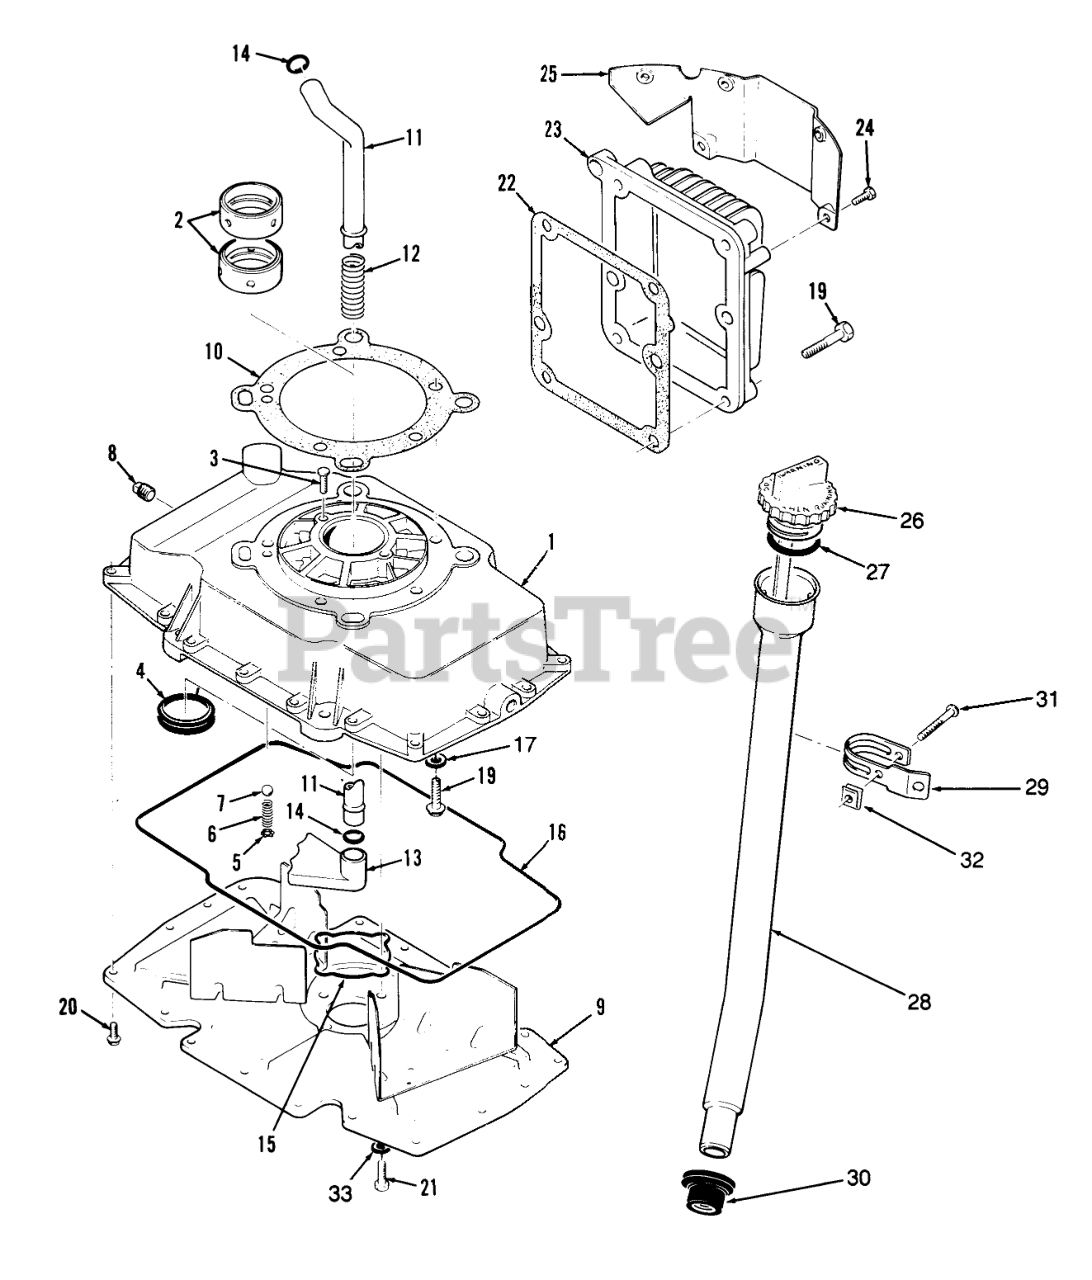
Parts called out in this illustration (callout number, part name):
1	Oil Base (Includes Items 2 thru 7)
2	BEARING KIT (STANDARD SLEEVE)
3	Screw
4	Oil Seal
5	RETAINING-RING
6	Spring
7	BALL-BEARING
8	Plug
9	OIL-BASE COVER ZINC
10	OIL-BASE GASKET
11	OIL-PICKUP TUBE
12	OIL-PICKUP SPRING
13	OIL-PICKUP CUP
14	"O" Ring
15	OIL-SEAL
16	OIL-SEAL
17	Washer
19	HEX-HEAD CAP SCREW
20	SCREW-HH
21	SCREW-HWH
22	Gasket
23	OIL-COOLER
24	HEX HD CAPSCREW
25	OIL-COOLER BAFFLE
26	OIL-LEVEL INDICATOR
27	SEAL 0-RING
28	OIL-FILL TUBE (ZINC)
29	SUPPORT-BRKT (ZINC)
30	Seal
31	Screw
32	Nut
33	WASHER
